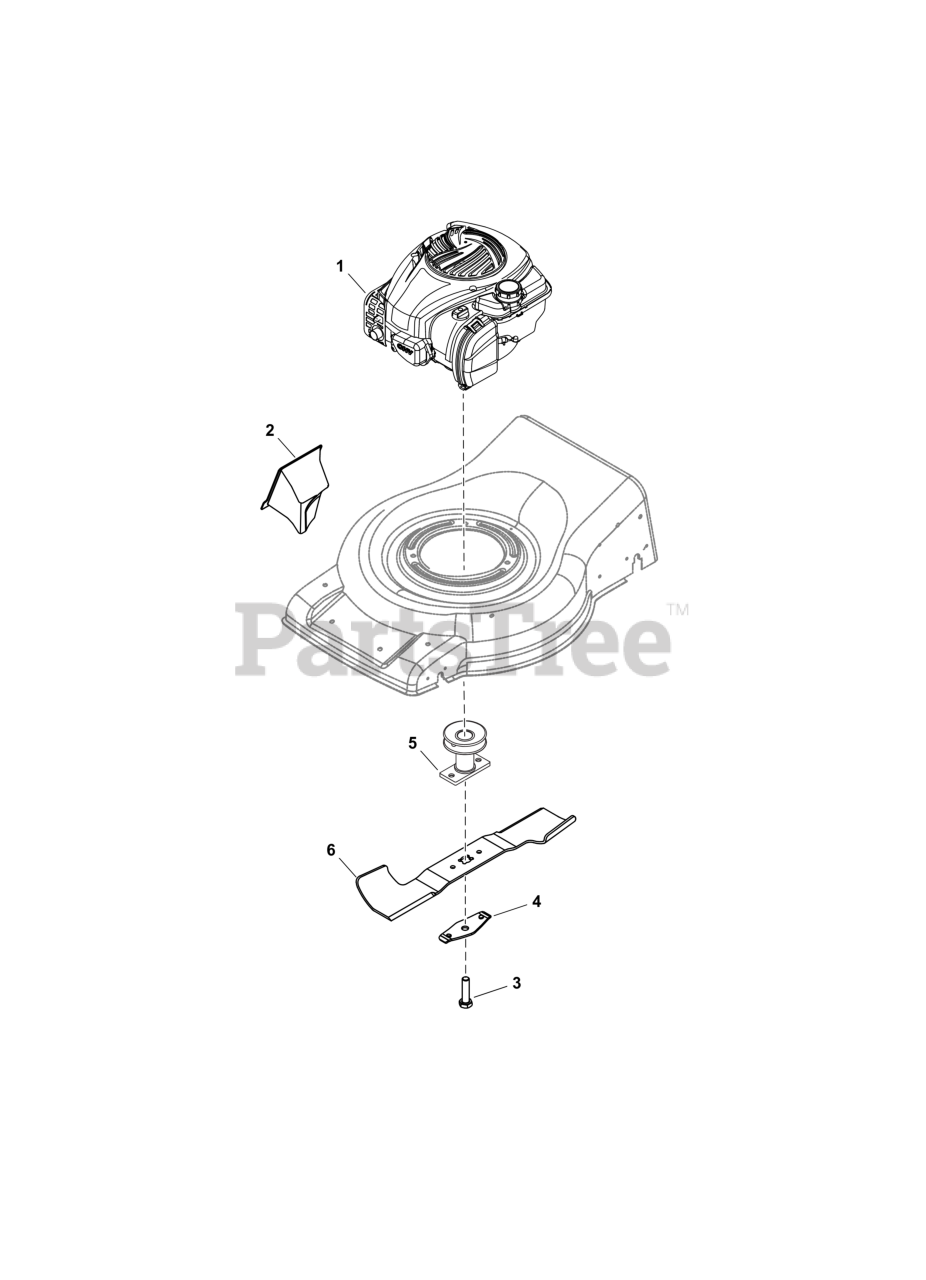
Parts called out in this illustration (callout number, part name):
2	MULCH PLUG
3	SCREW Hex, 3/8-24 x 1-1/2
4	SUPPORT, Blade Bell
5	BLADE ADAPTER
